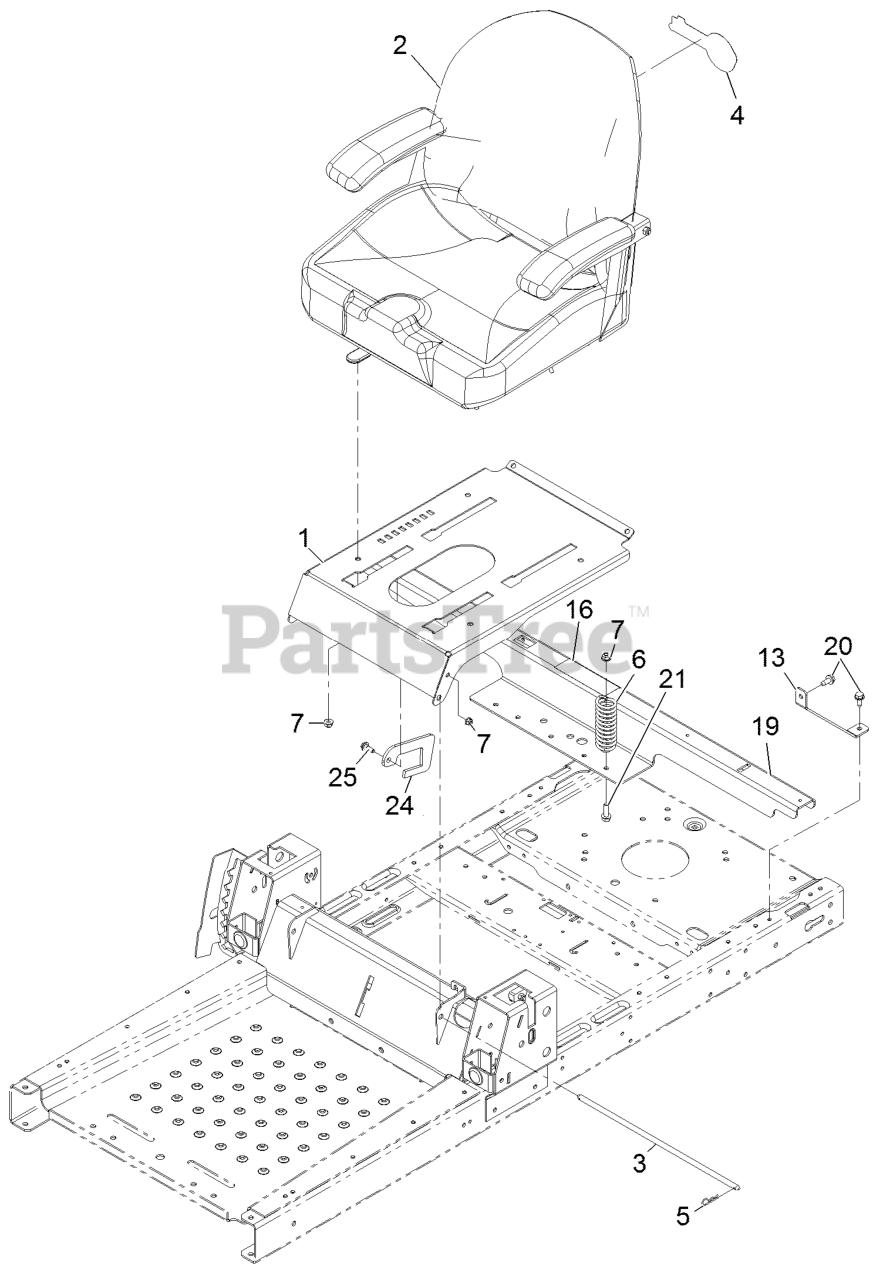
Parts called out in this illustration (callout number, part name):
2	SEAT ASM
3	ROD-STOP
5	PIN-COTTER
6	SPRING-COMPRESSION
7	NUT-HF, NI
13	SUPPORT-TANK, REAR
16	DECAL-SERVICE, CE
19	SUPPORT-POD
20	Screw-HWH 5/16-18 X 3/4 Tf
21	SCREW-HHF
24	STOP-SEAT
25	SCREW-SHOULDER
